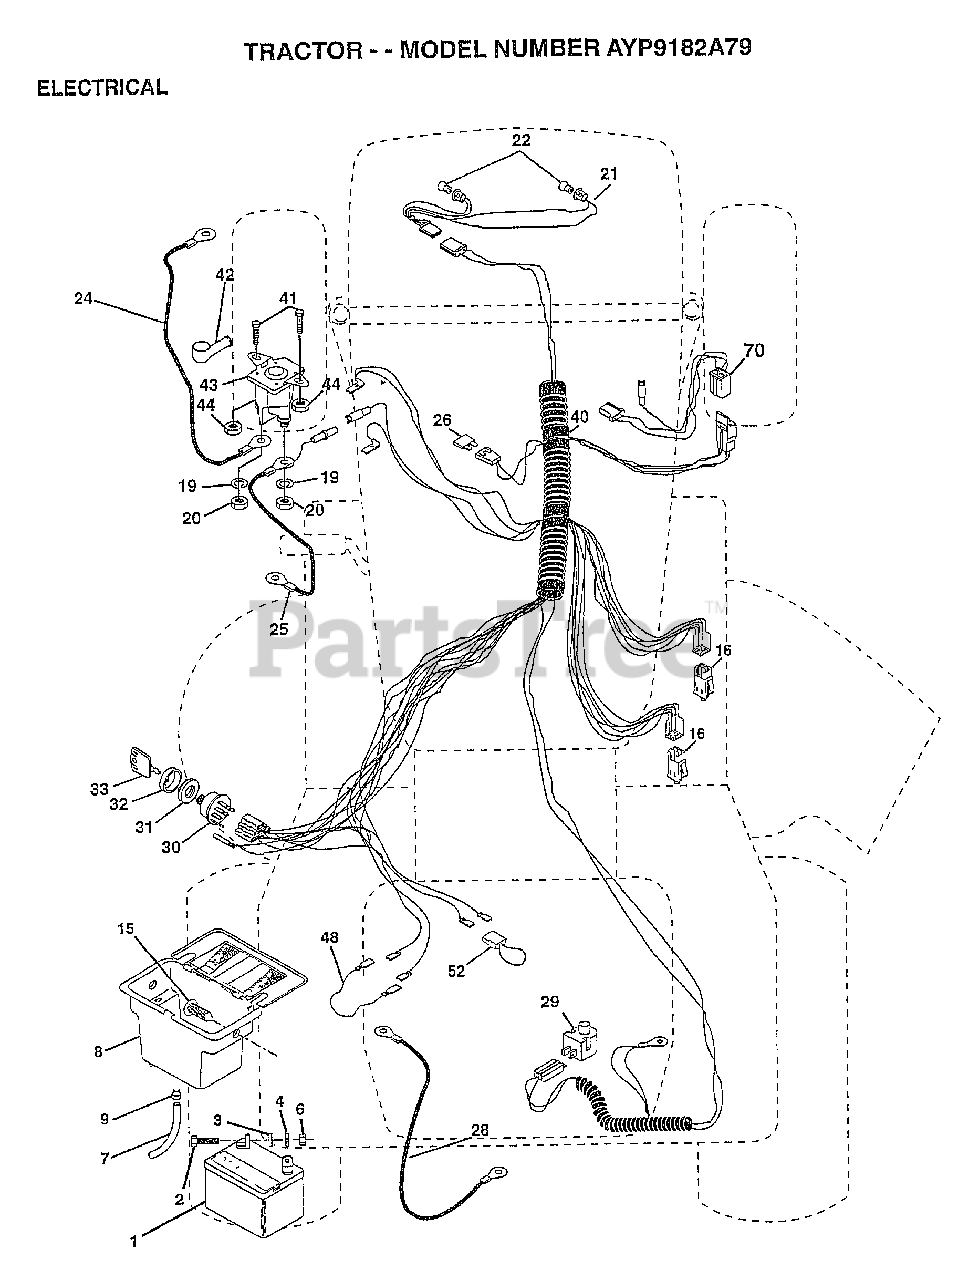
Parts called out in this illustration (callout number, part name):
2	BOLT LT
3	WASHER
4	LOCKWASHER
7	TUBE T
8	"CASE,BATTERY.MECH"
9	HOSE CLAMP T
15	FASTNER.SNAP-IN
16	SWITCH INTERLOCK
20	NUT
21	"HARNESS,LIGHT SOC"
22	HEADLAMP BULB
24	"CABLE T, BATTERY"
25	CABLE.BTRY.6GA.RD
26	FUSE HYT
28	CABLE T
29	SWITCH SEAT
30	SWITCH IGN 4POS
31	NUT IGNITION
32	COVER KEY SWITCH
33	KEY
40	HARNESS-IGNITION
41	BOLT HXHD FIN
44	NUT HXKEP 1/4X20
48	ADAPTER AMMETER
52	PROTECTION LOOP
70	HARNESS ENG DUAL
